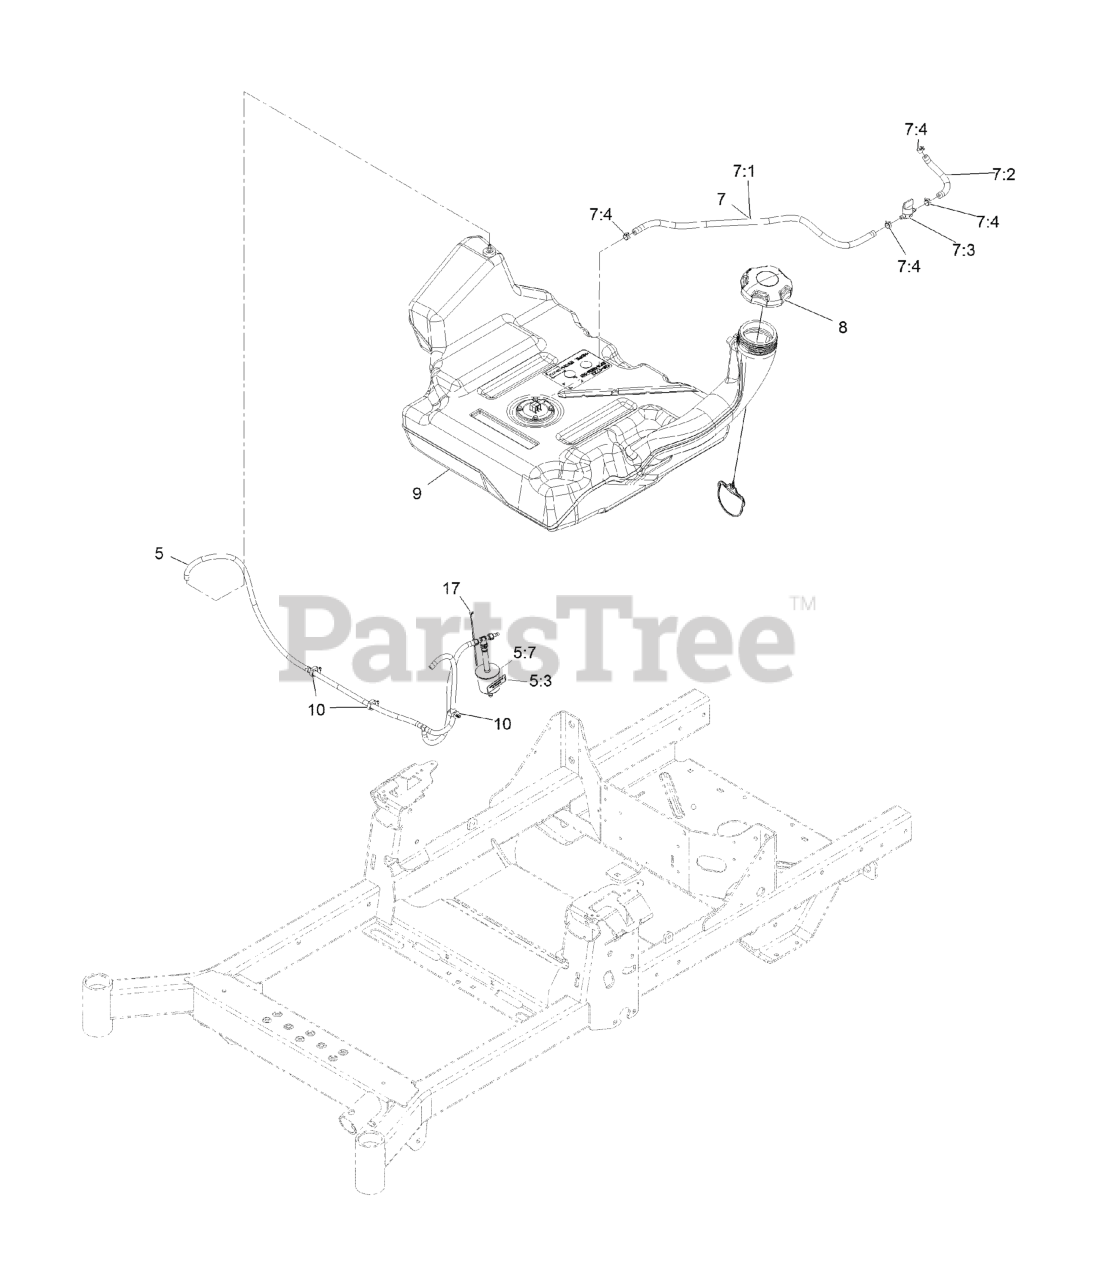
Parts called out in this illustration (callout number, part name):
5	VENT HOSE ASM
5:3	DECAL-FILTER, EMISSIONS
5:7	FILTER-FUEL
7	FUEL HOSE ASM
7:1	HOSE-FUEL
7:2	HOSE-FUEL
7:3	VALVE-FUEL
7:4	CLAMP-HOSE
8	CAP-FUEL, RATCHETING
9	TANK-FUEL
17	TIE-CABLE
